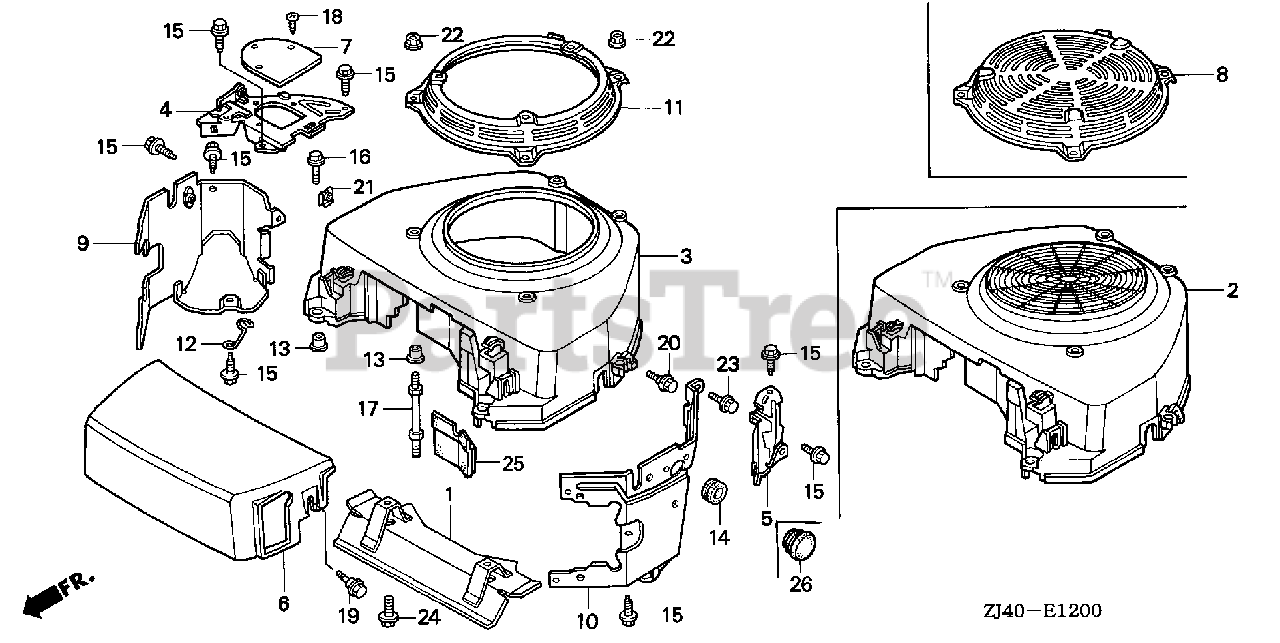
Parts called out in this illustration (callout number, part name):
1	PROTECTOR, EX. PIPE Use from Engine SN 1000016.
2	COVER, FAN *NH1* (BLACK)
2	COVER, FAN *R280* (POWER RED)
4	PLATE, SIDE
5	PLATE, SIDE
6	HOOD, FAN COVER
10	SHROUD, L.
12	CLAMP, IGNITION TUBE
13	COLLAR B, TAILLIGHT
14	RUBBER, BRACKET MOUNTING
15	BOLT, FLANGE (6X12) (CT200)
16	BOLT, FLANGE (6X23) (CT200)
17	BOLT, STUD (6X75)
19	BOLT, FLANGE (6X20)
20	BOLT, FLANGE (6MM) (BLACK)
21	NUT, SPRING (6MM)
22	NUT, FLANGE (6MM)
23	BOLT, FLANGE (6X8)
24	BOLT, FLANGE (8X16) Use from Engine SN 1000016.
